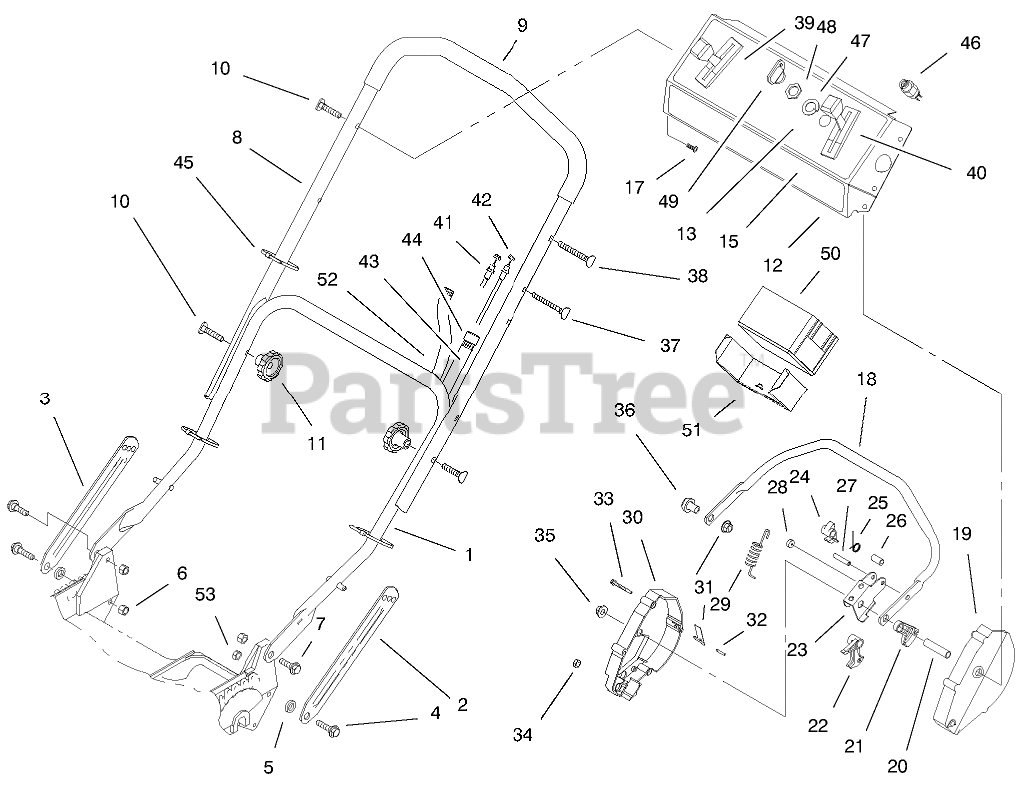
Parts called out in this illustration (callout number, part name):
1	ASM-Handle
2	Latch-Handle
3	Latch-Handle
4	SCREW-SHOULDER
5	SPACER
6	NUT-LOCK, NI
7	SCREW-SHOULDER
8	Handle-Upper
9	Grip-Foam
10	SCREW-HANDLE
12	Panel-Control(Incl. Ref. #13)
13	DECAL - INSTRUCTION
15	DECAL - FRT PANEL
17	SCREW-TAP
18	Bar-Control
19	HOUSING-CONTROL, LH
20	TUBING-SPACER
21	LEVER-TRACTION
22	ROCKER
23	LEVER-CABLE
24	HOOK-CONTROL
25	SPRING-TORSION
26	SPACER
27	PIN-ROLL, SLOTTED
28	WASHER-NYLON
29	SPRING-DETENT
30	Housing-Control
31	SPRING-LEAF
32	PIN-INSERT
33	SCREW-HWHTF
34	NUT-LOCK NI
35	NUT-LOCK NI
36	SPACER-SUPPORT
37	SCREW-HANDLE
38	OBS MATERIAL EXCEPT FOR SERVICE
39	CONTROL-SPEED, GROUND
40	THROTTLE CONTROL
41	CLUTCH CABLE
42	TRACTION CABLE
43	CONTROL CABLE COVER
44	FITTING-RING
45	TIE-CABLE
46	Switch-Starter(Incl. Ref. #47 & 48)
47	WASHER-TOOTH, INTERNAL
48	NUT-HH
49	KEY-IGNITION
50	BATTERY ASSEMBLY
51	Retainer-Battery
52	Harness-Wire
53	NUT-LOCK, NI
